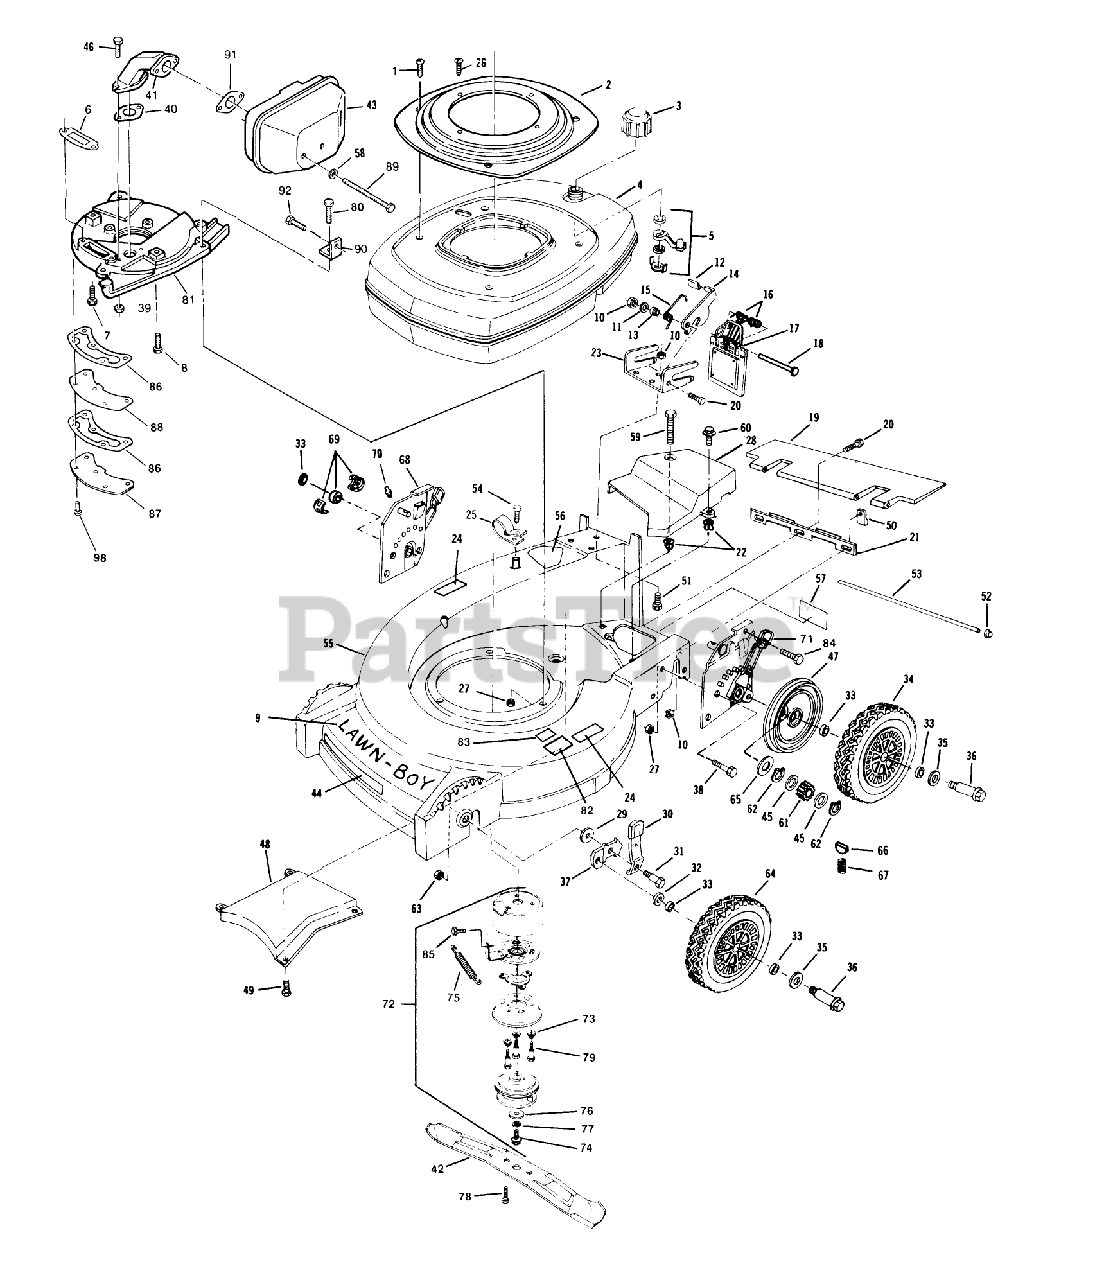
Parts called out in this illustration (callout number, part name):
3	FUEL CAP & INSERT
5	SHUT-OFF VALVE S
8	SCREW V
10	LOCKNUT E
12	KNOB (S&R)
15	SPRING
16	SPRING ASOC
18	ROD (RB&W)
19	T/SHIELD SM&P
26	SCREW SEMS SM
27	NUT-LOCK F
29	WASHER
30	SPRING ARM ASM
31	BOLT
32	WASHER WROUGHT
33	WASHER
35	SPACER
36	BOLT WHEEL
39	LOCKNUT E
45	SPACER/GR ALGHNY
48	BAFFLE CHUTE PL
54	SCREW LAWRENCE
60	SCREW
61	PINION BROCKWAY
62	RET RING
63	LOCKNUT
64	WHEEL&TIRE 8" TRI
65	THRUST WASHER
66	KEY
67	SPRING
69	REAR AXLE BEARING
70	**FITTING LINCOLN
75	SPRING
76	WASHER
78	SCREW SEMS
79	SCREW,SHOULDER SM
80	SCREW
82	PAD FOOT
86	GASKET S
87	COVER HIP
91	GASKET S
92	SCREW-SEMS
